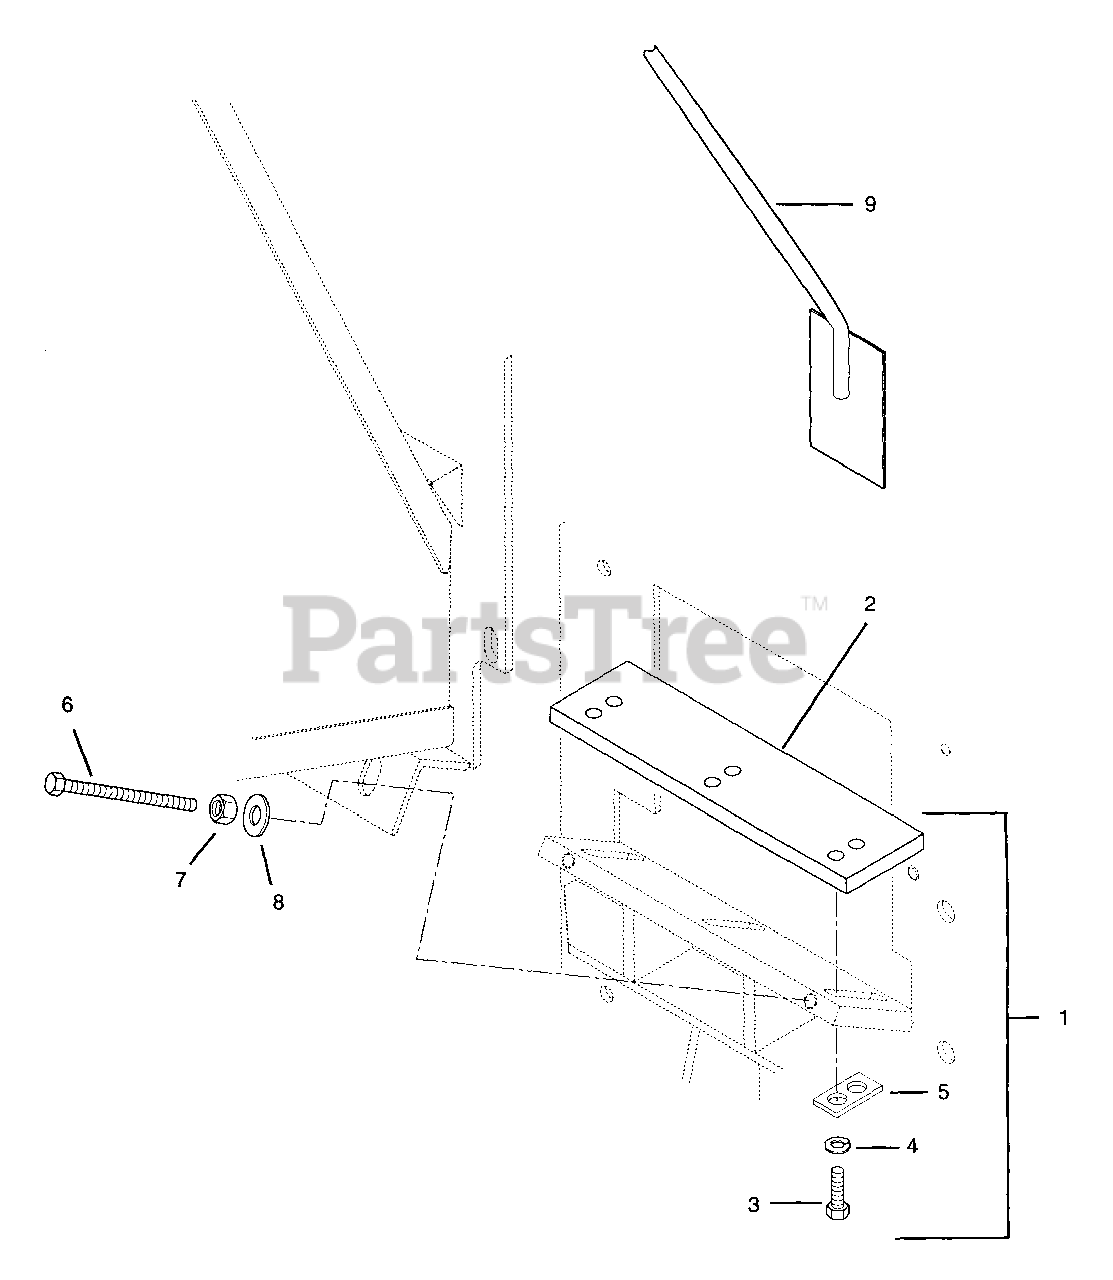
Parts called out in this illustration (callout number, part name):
1	Bed Knife Kit - 210/PTO6/618R
3	Bolt-Hex .38-16 x 1.25 Grade 8
4	Washer-Lock .38 x .094
5	Double Hole Washer
6	Bolt-Hex .38-16 x 3.50 Full Thread
7	Nut-Hex .38-16
8	Washer-Flat-Steel .438 x 1.00 x .083
9	Knife Gauge
